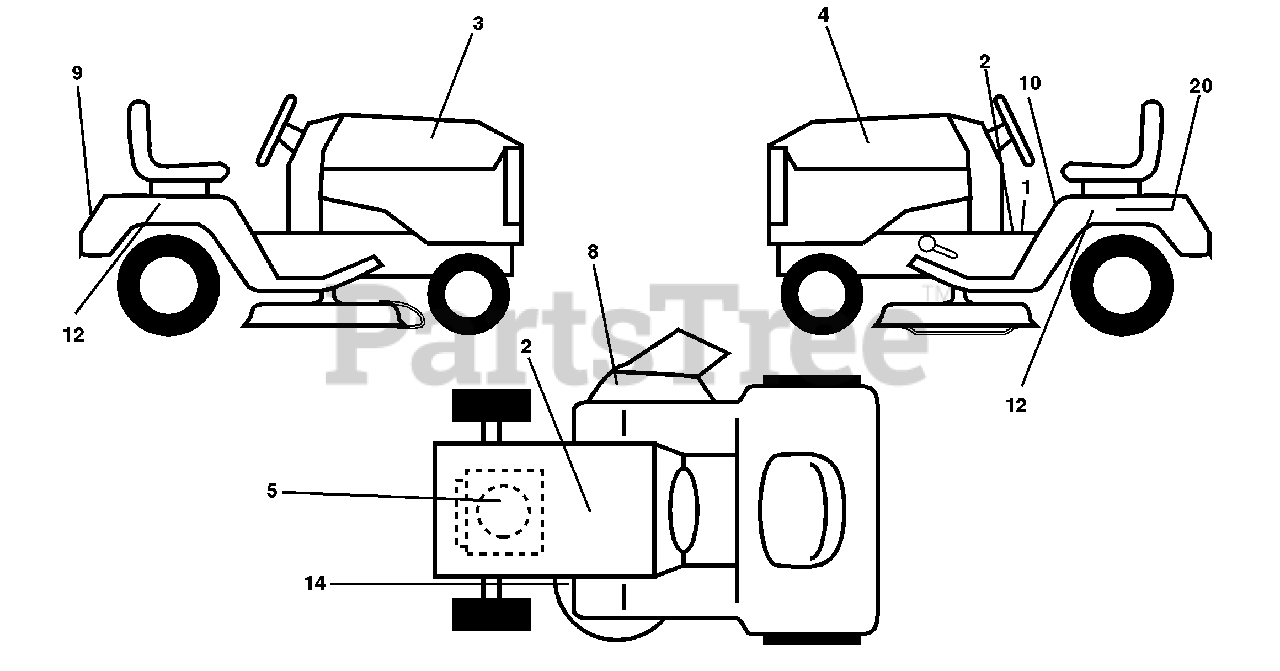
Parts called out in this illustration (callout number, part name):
1	Decal Oper. Step Thru E/F
2	Decal Battery
3	Decal Hood LH
4	Decal Hood RH
5	Decal HP Engine
8	Decal Warning Multi-Languages
9	Decal Fender Husq
10	Decal Fender Danger E/F
12	Decal Fender Auto Husq Radius
14	Decal V-Belt Schematic
